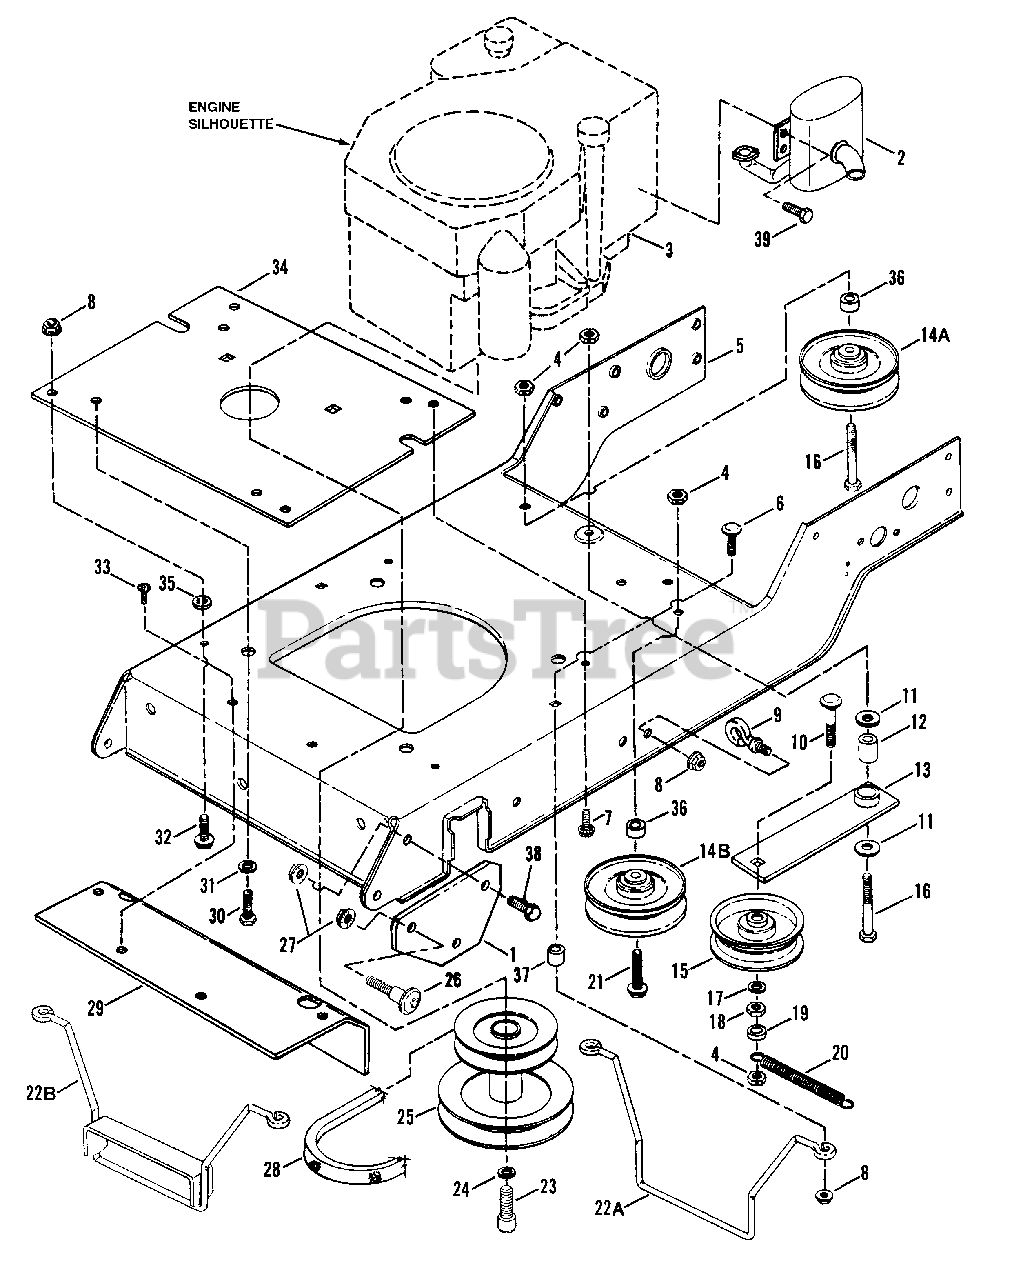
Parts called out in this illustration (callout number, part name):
1	BRACKET, Hood
2	MUFFLER, Exhaust
4	NUT, 3/8-16 Hex Center Lock
5	BASE, Engine
6	BOLT, 5/16-18 x 3/4" Short Neck Carriage
6	BOLT, 5/16-18 x 1 1/2" Carriage (38" Models Only)
7	BOLT, 5/16-18 x 3/4" Flange Lock
8	NUT, 5/16-18 Hex Flange Lock
9	EYE-BOLT
10	BOLT, 3/8-16 x 2 1/2" Short Neck Carriage
11	WASHER, 3/8" Flat
12	BUSHING, Idler Arm .750 OD x .406 ID x .75 L
13	ARM, Idler
14A	PULLEY, Idler, 3.56" O.D.
14B	PULLEY, Idler, 4" O.D.
15	PULLEY, Idler, 3 3/4" O.D.
16	BOLT, 3/8-16 x 2 1/4" Hex
17	WASHER, 318 Split Lock
18	NUT, 3/8-16 Hex
19	SPACER .623 OD x .38 ID x .25 L
20	SPRING, Idler Arm
21	BOLT, 3/8-16 x 1 3/4" Hex Flange Lock
22A	GUIDE, Belt (42" & 48" Models Only)
22B	GUIDE, Belt (38" Models Only)
23	SCREW, M10-1.50 x 25mm Hex Head Cap
24	WASHER, SLW 7/16" YZ
25	ASSEMBLY, Engine Pulley
26	SCREW, 3/8-16 x 1 1/4" Shoulder (Torx)
27	NUT, 3/8-16 Hex Flange Lock
28	V-BELT, Traction Drive A113.6
29	SUPPORT, Axle (No longer available)
30	BOLT, M8-1.25 x 25mm Hex Head
31	WASHER, 5/16 Split Lock
32	BOLT, 5/16-18 x 1" Hex Flange Lock
33	SCREW, 5/16-18 x 7/8" Truss Head (Torx)
34	SPACER, Kohler Engine
35	RETAINER, 5/16 Bolt
36	SPACER .750 OD x .390 ID x .5 L
37	SPACER, .81 OD X .48 ID x .5 L (38" Models Only)
38	SCREW, 3/8-16 x 3/4" Hex Head Cap
39	SCREW, 1/4-20 x 1/2" Hex Head Cap, Grade 5
